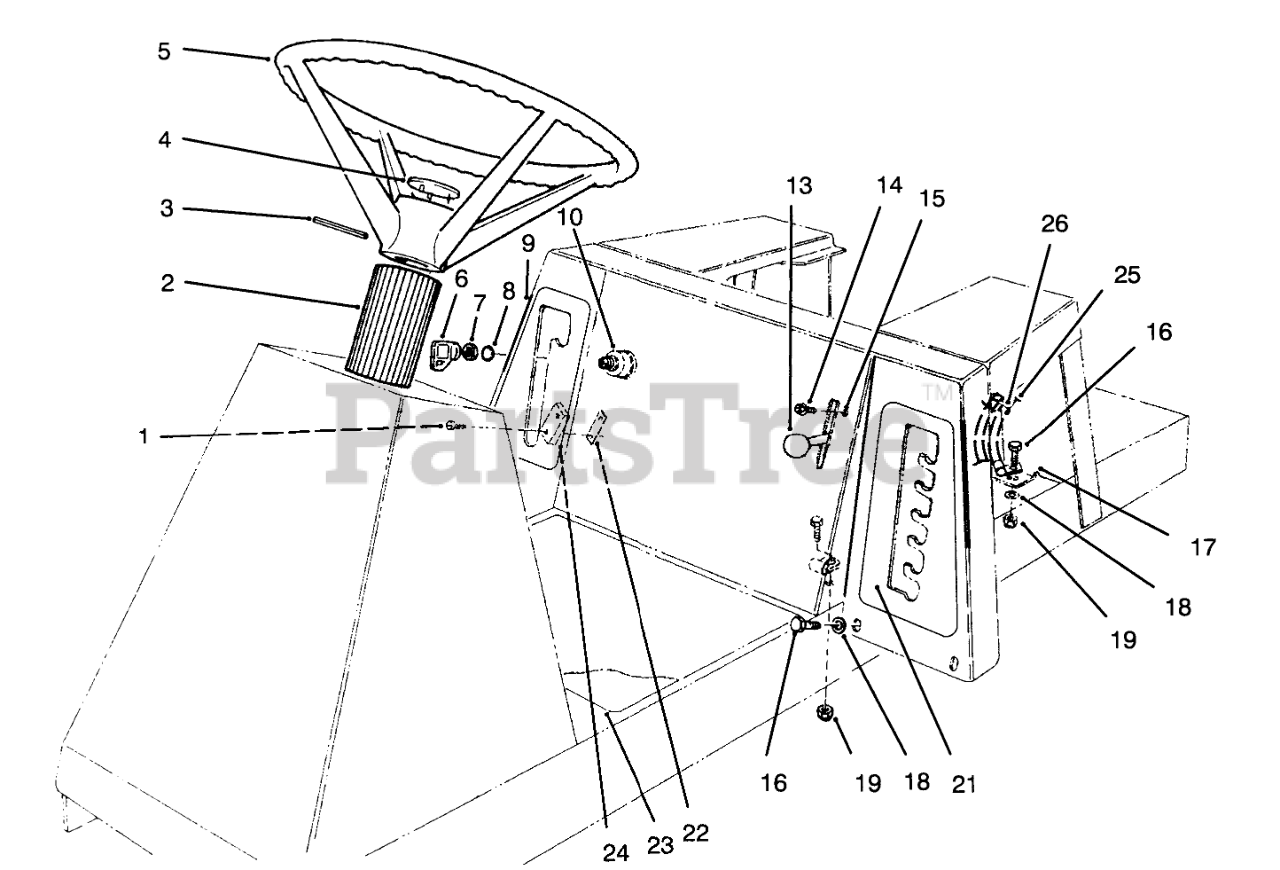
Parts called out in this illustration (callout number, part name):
1	SCREW-HH
2	COVER-STEERING SHAFT
3	PIN-ROLL
4	INSERT - STRG WHL F/W
5	Assy.-Wheel, Steering (Incl. Ref. #4)
6	KEY-IGNITION
7	NUT-HH
8	WASHER-TOOTH, INTERNAL
9	DECAL - DECK ENGAGE
10	Switch-Ignition (Incl. Ref. #6-8)
13	KNOB-CONTROL
14	SCREW-HWHTF
15	Control-Throttle (Incl. Ref. #13)
16	SCREW-HH
17	CLIP
18	WASHER-PLAIN
19	NUT-LOCK, NI
21	DECAL - HOC
22	NUT-SPEED
23	INSTRUCTION DECAL
24	SWITCH-MICRO
25	WIRE ASM
26	TIE-CABLE
